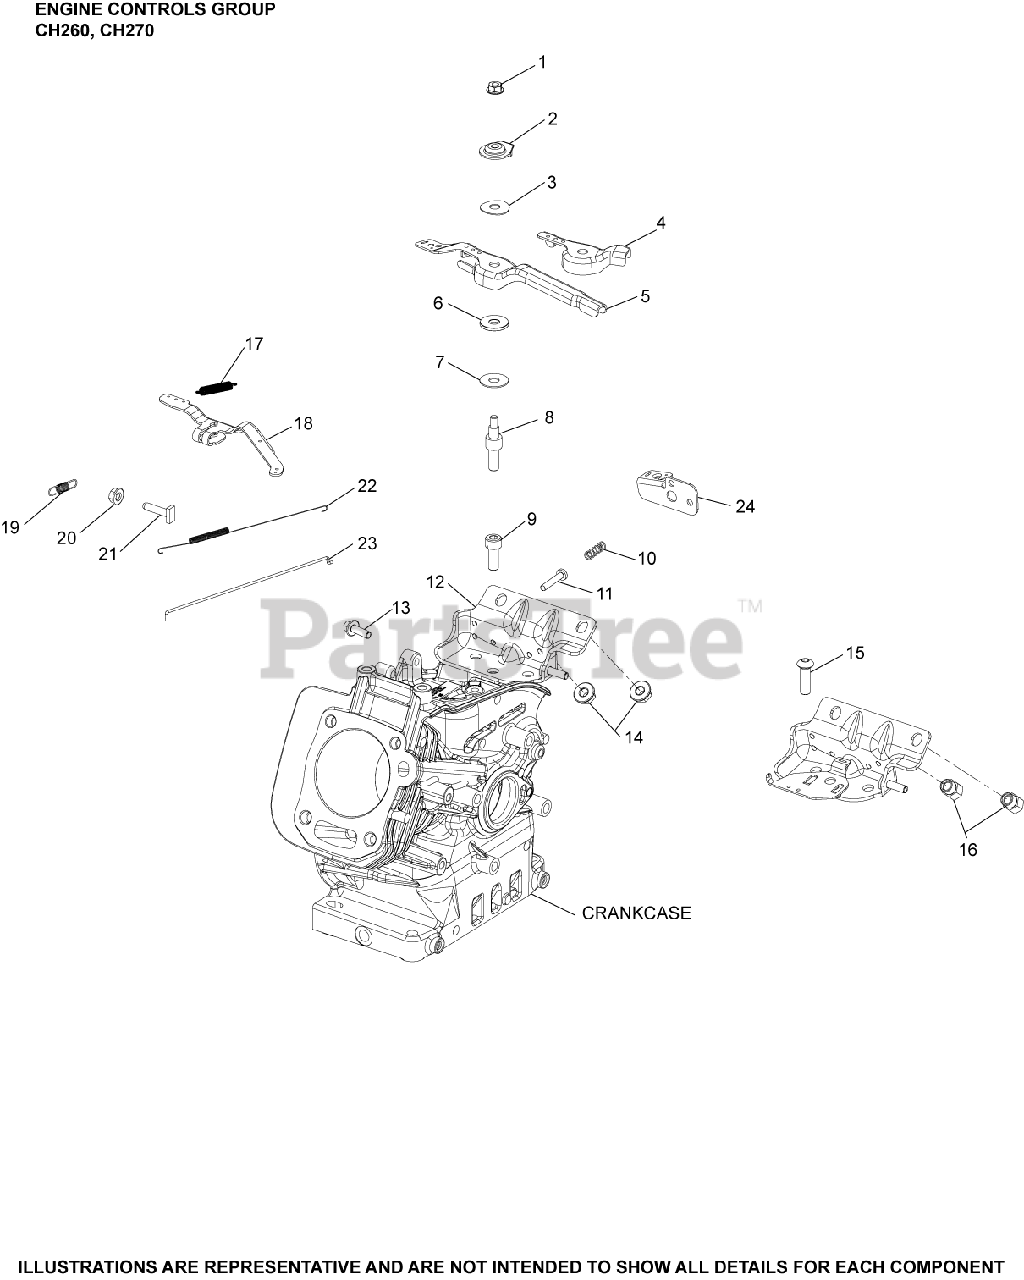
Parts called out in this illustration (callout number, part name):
2	WASHER, CONTROL LEVER
3	WASHER, SPRING
5	LEVER, CONTROL THROTTLE
6	WASHER, NYLON CONTROL LEVER
7	WASHER, FLAT
8	STUD, CONTROL LEVER
10	SPRING, COMPRESSION
11	SCREW, SPEED ADJUSTING
12	BRACKET, FUEL AND CONTROLS
14	NUT, FLG M8X1.25
18	KIT, GOVERNOR LEVER
19	SPRING, GOVERNOR
21	SCREW, RECTANGLE HEAD (M6)
22	SPRING, LINKAGE
23	LINKAGE, GOVERNOR
24	BRACKET, CABLE CLAMP
25	CLAMP, CABLE
